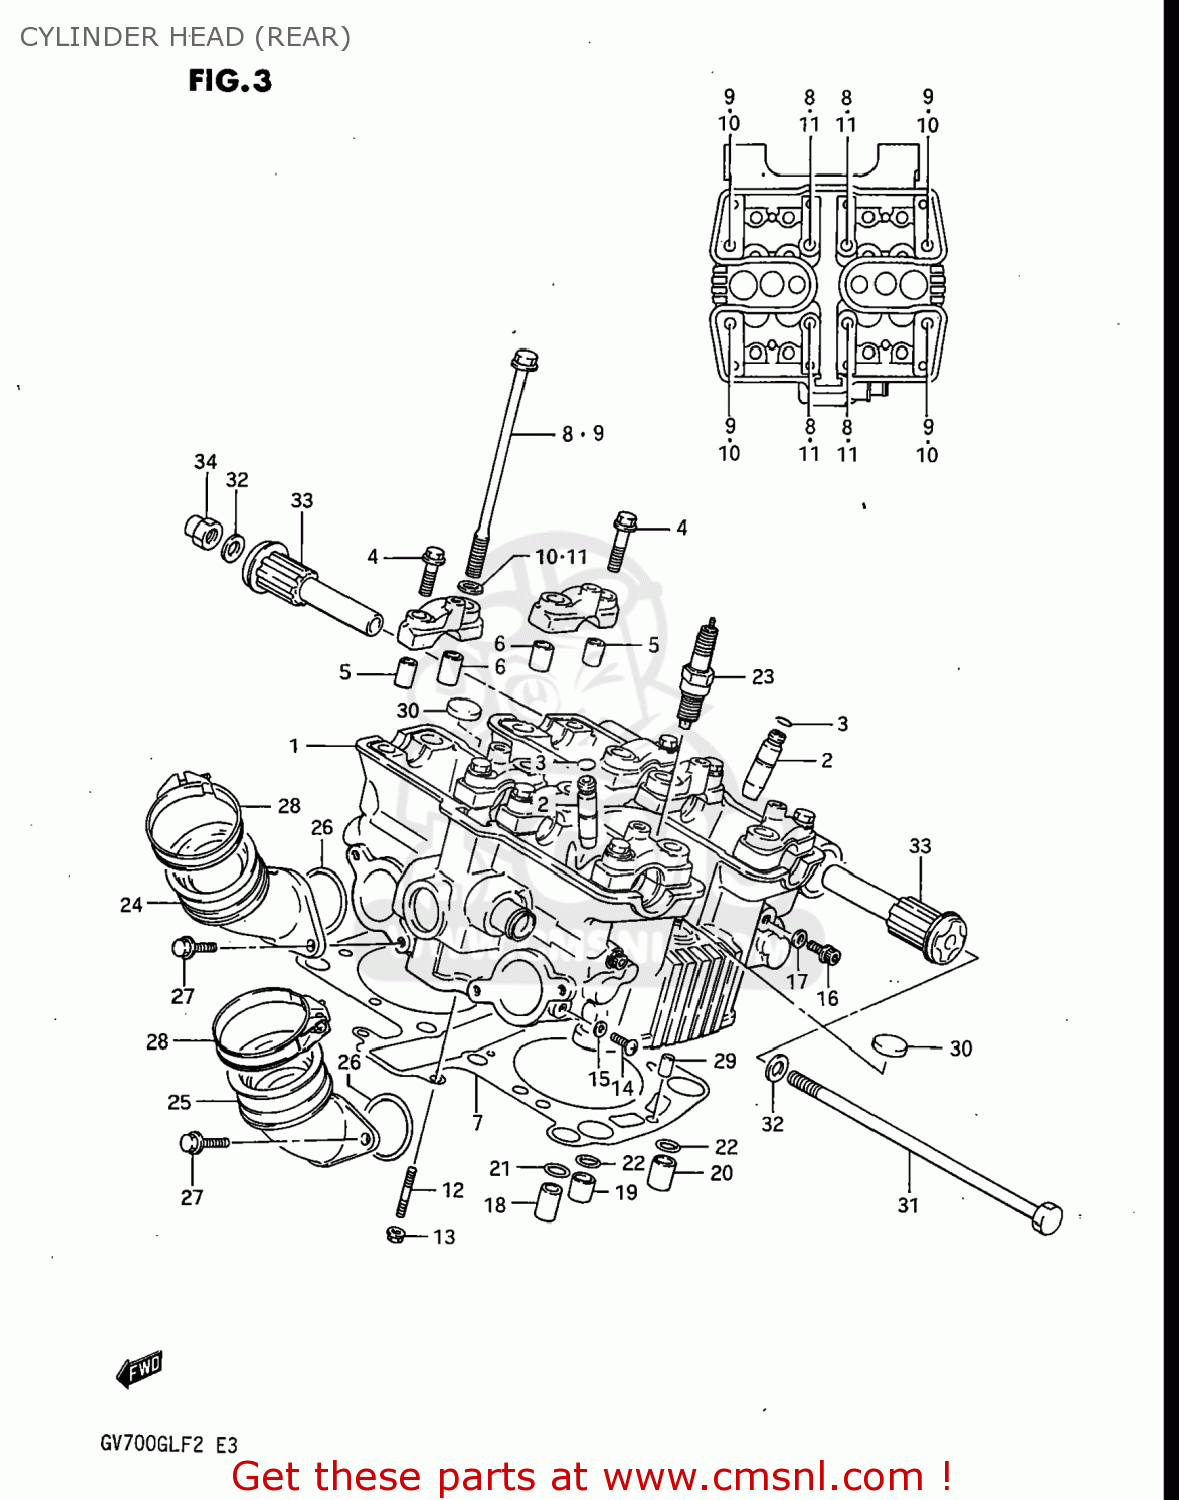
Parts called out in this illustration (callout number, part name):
1	HEAD ASSEMBLY,CYLINDER,REAR
2	GUIDE,VALVE
3	RING,SNAP
4	BOLT
5	PIN (11X20)(SUS)
6	PIN(10.4X13X22)
7	GASKET,CYLINDER HEAD,REAR (MCA)
8	BOLT
9	BOLT
10	WASHER
11	WASHER (10X20X2.3)
12	STUD 6X25
13	NUT 6MM
14	SCREW
15	GASKET(5.3X9.3X1.2) (NAS)
16	BOLT
17	GASKET(6.2X13X1.2) (NAS)
18	PIN(6.4X9X20)
19	PIN
20	PIN
21	O RING(D:1.9,ID:8.6)
22	O RING(D:1.9,ID:12.6)
23	SPARK PLUG D8EA
24	NET,INTAKE
25	PIPE,INTAKE
26	O RING(D:2.4,ID:35)
27	BOLT
28	CLAMP,PIPE
29	PIN
30	PLUG
31	BOLT
32	WASHER
33	BUSHING,ENGINE MOUNT
34	NUT
